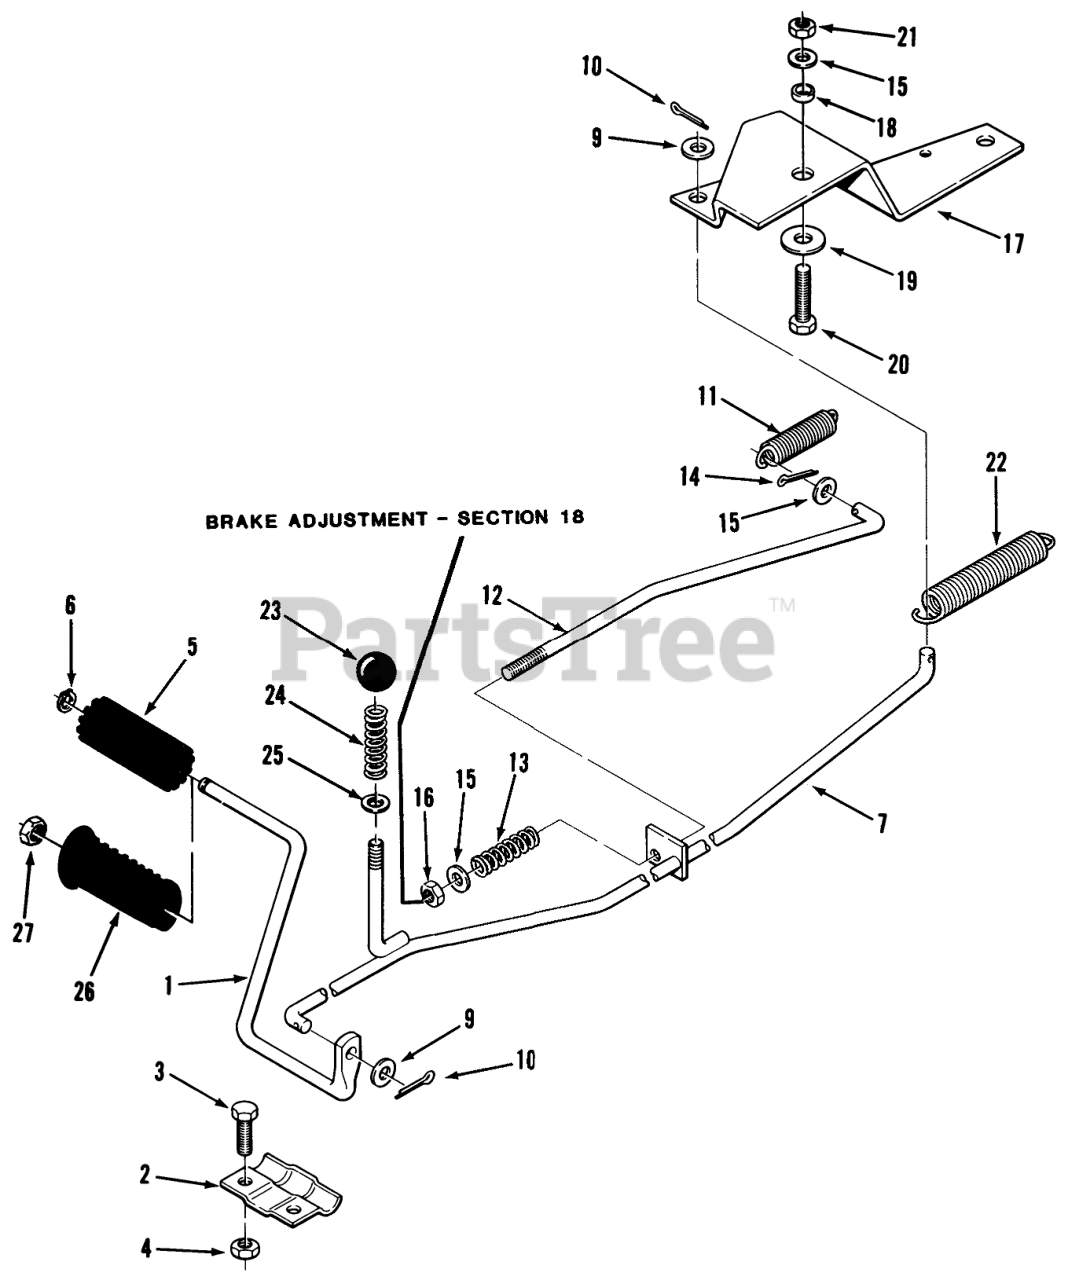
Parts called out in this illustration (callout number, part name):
1	ROD-BRAKE PEDAL R
2	SPINDAL SUPPORT R
3	Bolt
4	NUT
5	PAD-CLUTCH/BRKE PDL
6	Grip Ring
7	ASSY CLUTCH ROD
9	Washer
10	Cotter Pin
11	SPRING-EXTENSION
12	ROD BRAKE
13	SPRING-COMPRESSION
14	Cotter Pin
15	Washer
16	NUT
17	LEVER CLUTCH R
18	SPACER
19	WASHER
20	Bolt
21	NUT
22	SPRING EXTENSION
23	KNOB
24	SPRING
25	WASHER
26	Clutch/Brake Pedal 112-C Only
27	Jam Nut
